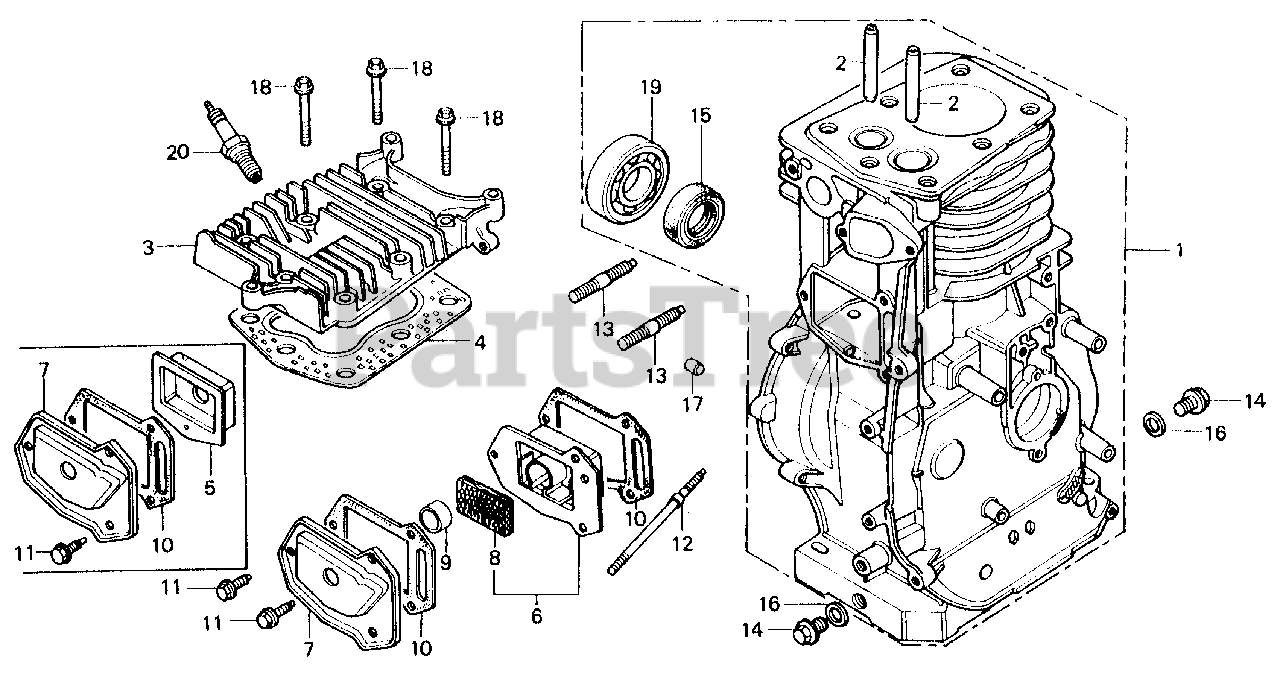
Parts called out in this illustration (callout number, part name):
1	CYLINDER ASSY.
2	GUIDE, VALVE (OS)
3	CYLINDER HEAD
4	GASKET, CYLINDER HEAD
5	CASE, BREATHER
6	CASE, BREATHER
7	COVER, TAPPET ROOM
8	FILTER, BREATHER
9	SEAL, BREATHER
10	GASKET, TAPPET COVER
11	BOLT, FLANGE (6X12) (CT200)
12	BOLT, STUD (6X96)
12	BOLT, STUD (6X89)
13	BOLT, STUD (8X35)
14	BOLT, DRAIN PLUG
15	OIL SEAL (25X41X6)
16	WASHER, DRAIN PLUG (12MM)
17	PIN A, DOWEL (8X14)
18	BOLT, FLANGE (8X45)
19	BEARING, RADIAL BALL (6205)
20	SPARK PLUG (BR-4HS) (NGK)
20	SPARK PLUG (W14FR-U) (DENSO)
